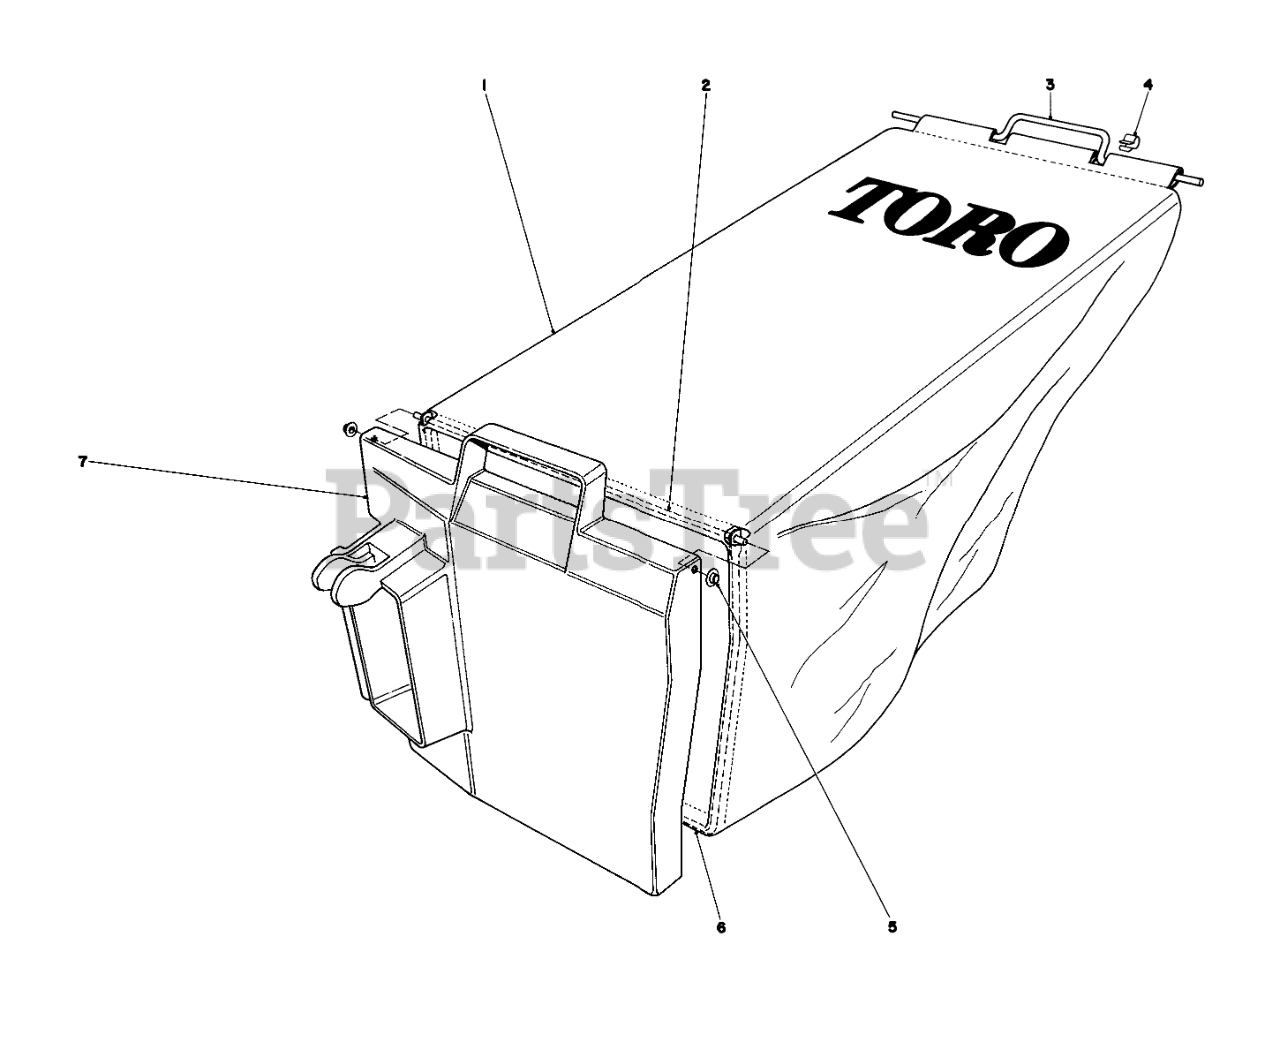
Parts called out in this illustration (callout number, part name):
1	18 BAGGER BAG 33-4552
2	HINGE
3	Handle Bag
5	NUT-PUSH
6	Frame Bag
7	Door-Bag
